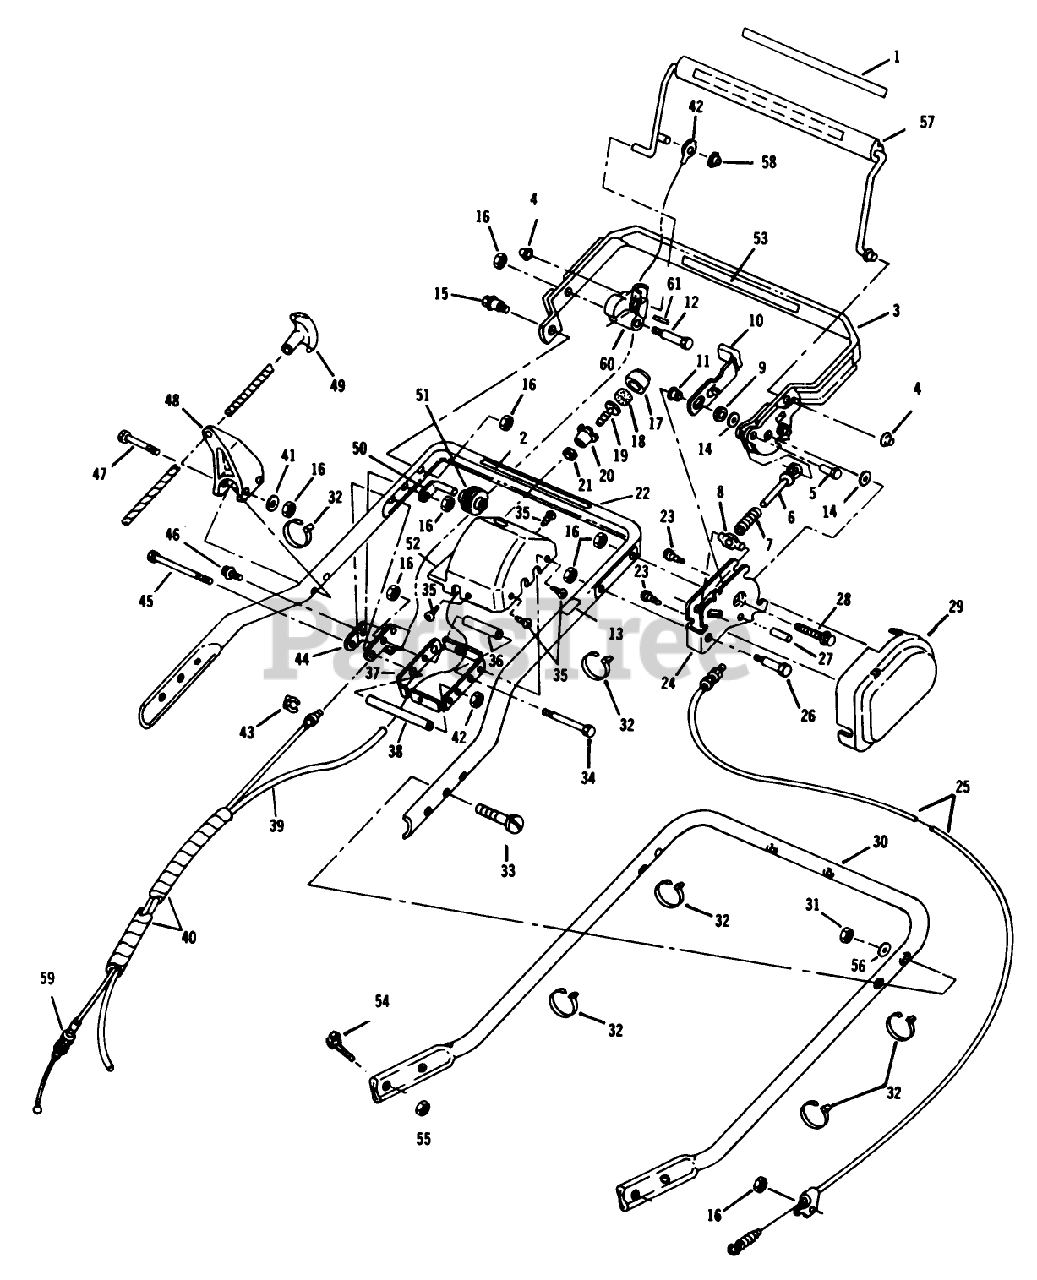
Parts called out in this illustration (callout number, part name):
9	WASHER M
15	BOLT
16	LOCKNUT E
18	FILTER S
21	LOCKNUT S
25	CABLE ASM
30	HANDLE AY-LOWER (12)
31	NUT-LOCK F
35	SCREW F
36	SPACER
41	WASHER
43	RET. RING
45	BOLT-CONSOLE
49	HANDLE,STARTER
55	LOCKNUT
56	WASHER-CURVED
58	NUT ACORN
59	CONTROL CABLE
